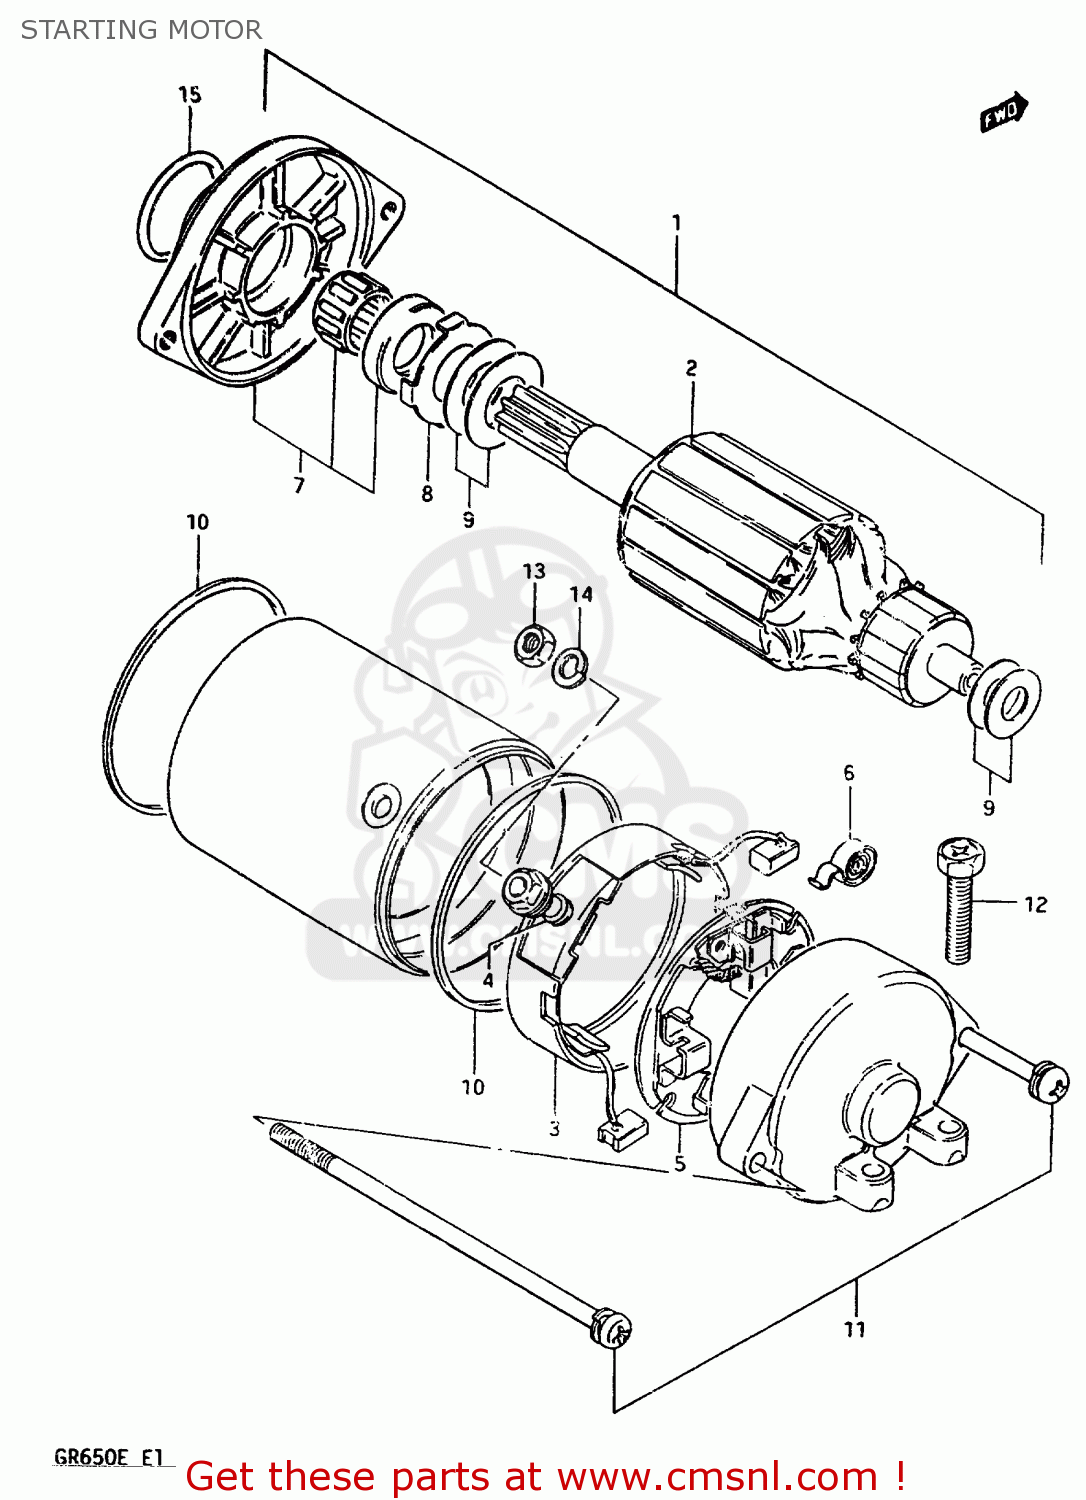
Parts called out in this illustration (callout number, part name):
1	MOTOR ASSEMBLY,STARTING
2	ARMATURE
3	BRUSH TERMINAL SET (+)
4	O RING
5	HOLDER,BRUSH
6	SPRING,BRUSH
7	BRACKET SET,STARTING MOTOR
8	SHIM SET
9	SHIM SET
10	SEAL,RING
11	BOLT
12	SCREW (6X25)
13	NUT
14	WASHER,LOCK
15	O RING(D:3,ID:24.5)
